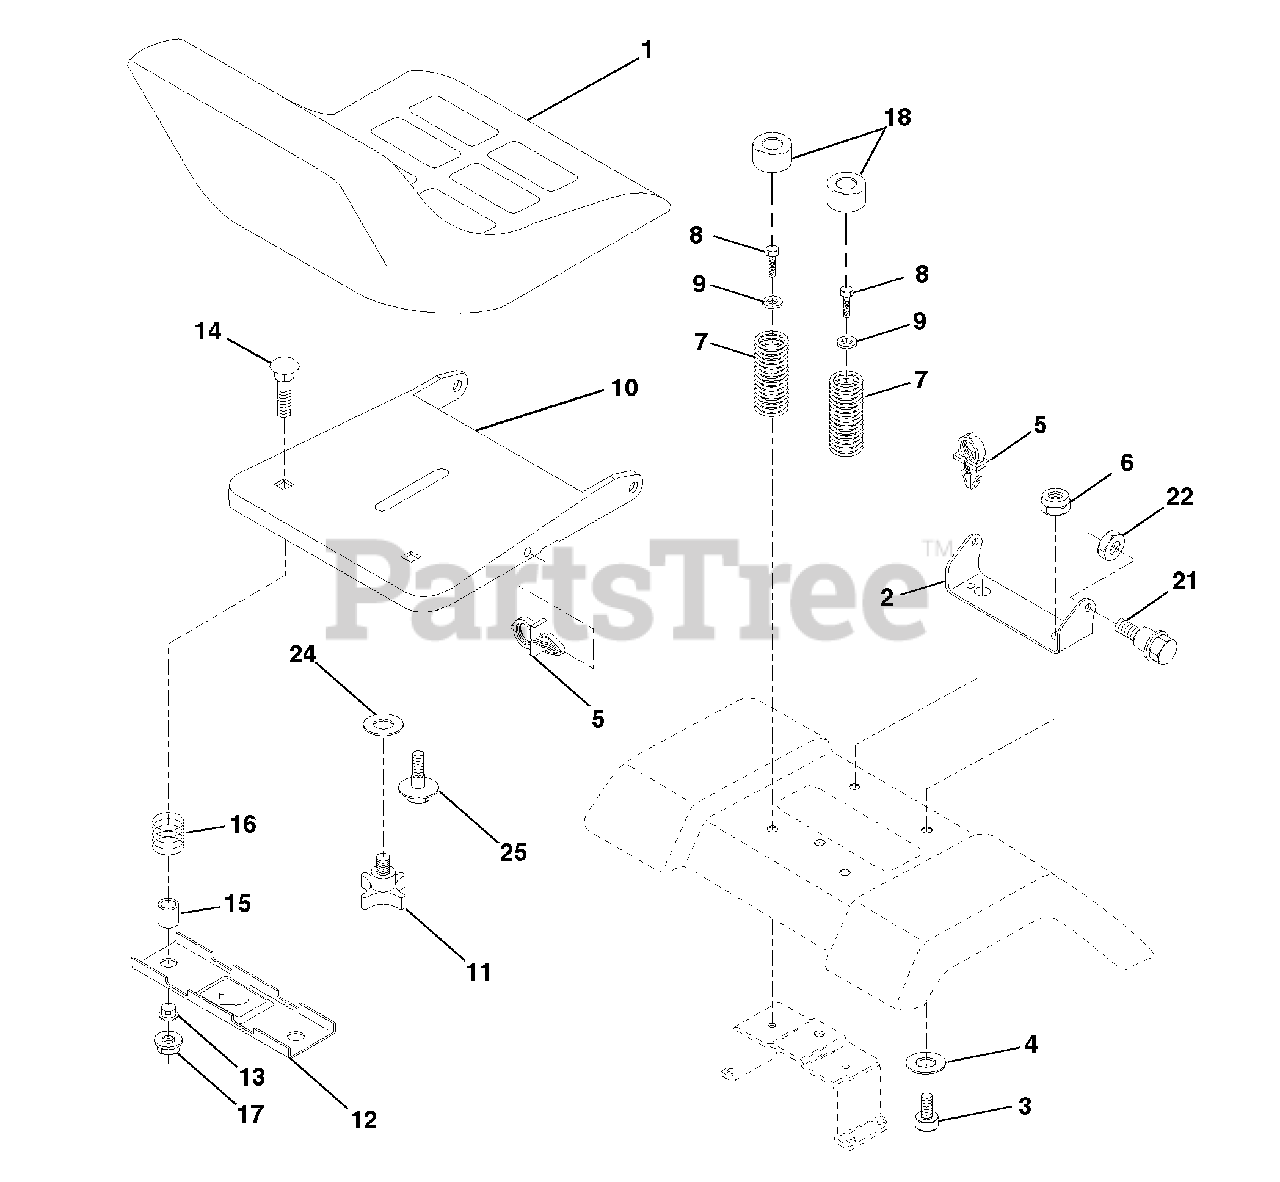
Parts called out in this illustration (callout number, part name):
1	Seat
2	Bracket Pivot Seat 8 720
3	Bolt Fin Hex 3/8-16 unc X 1
4	Washer 13/32 X 1 X 10 Ga
5	Clip Push-In
6	Nut Hex w/Ins. 3/8-16 Unc
7	Spring Seat Cprsn 2 250 Blk Zi
8	Screw Thdrol 3/8-16 X 1 Ty-tt
9	Washer 13/32 X 1 X 14 Ga.
10	Pan Seat
11	Knob Seat 1/2-13 UNC Blk
12	Bracket Mounting Switch
13	Bushing Snap Blk Nyl 50 Id
14	Bolt Rdhd Sqnk 1/4-20 x 1-3/8
15	Spacer Split 28 x 96 Yel Zinc
16	Spring Cprsn 1 27 Blk Pnt
17	Nut Lock 1/4 Lge Flg Gr 5 Zinc
18	Cap Spring Seat
21	Bolt Shoulder 5/16-18 Unc
22	Nut Hex Lock W/Ins 5/16-18
24	Washer 17/32 X 1-3/16 X 12 Ga.
25	Bolt Shoulder 5/16-18 X 62
